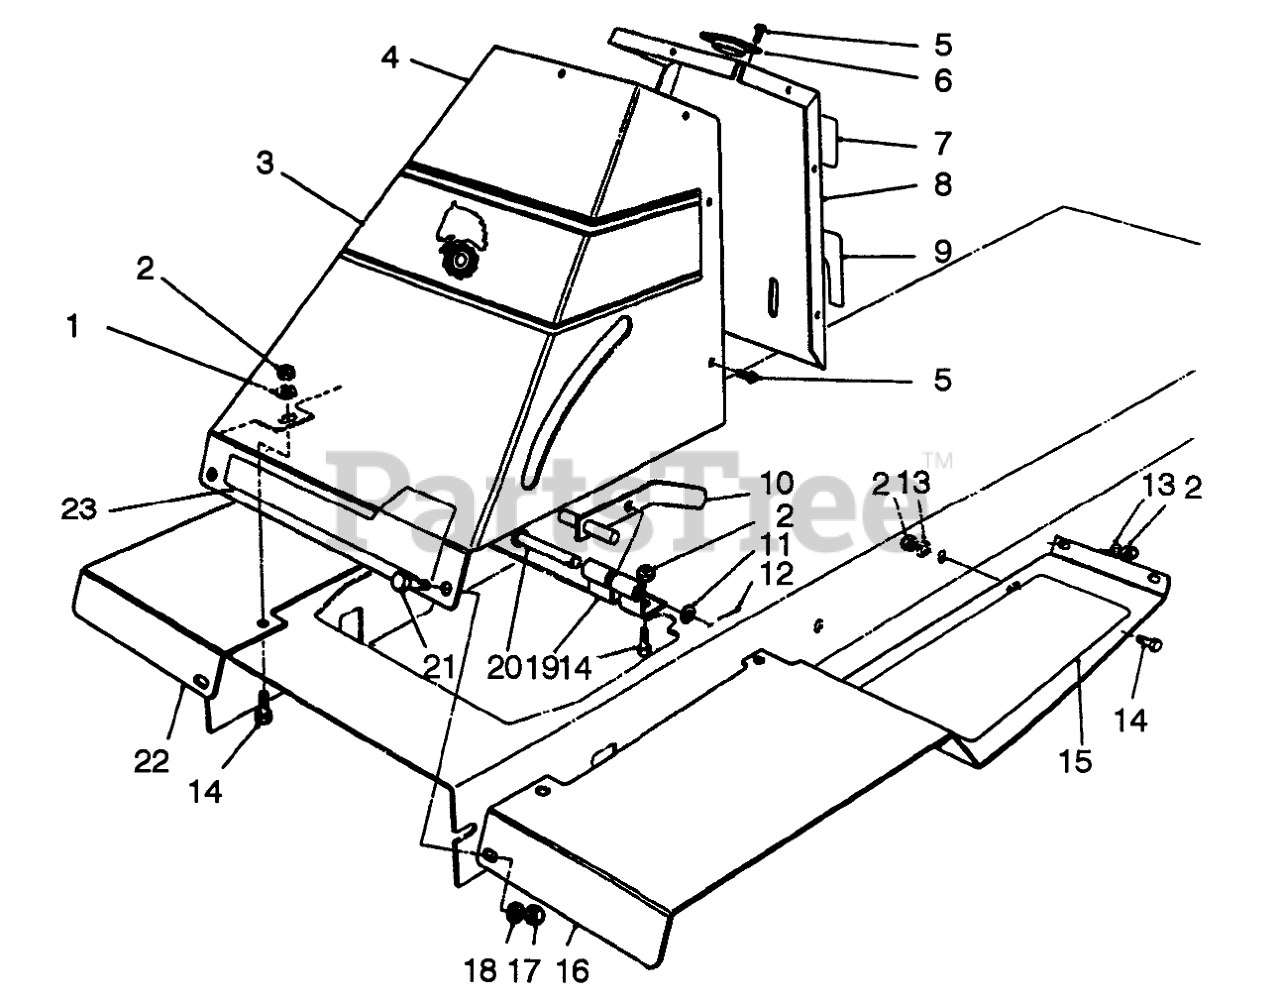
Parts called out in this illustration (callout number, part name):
1	WASHER-FLAT
2	NUT-LOCK, NI
3	DECAL - STEERING SUPT
4	Tower-Front
5	SCREW-HWHTF
6	GUIDE-STRG SHAFT
7	DECAL-DANGER
8	Tower-Rear
9	PARK BRAKE DECAL
10	PARKING BRAKE WA B
11	WASHER-FLAT
12	PIN-COTTER
13	WASHER-PLAIN
14	SCREW-HH
15	FOOT TREAD L.H.
16	Footrest-LH
17	NUT-LOCK, NI
18	WASHER-FLAT
19	Bracket-Parking Brake
20	PIN-CLEVIS
21	SCREW-HH
22	Footrest-RH.
23	DECAL/RECYCLER 32" FRT
